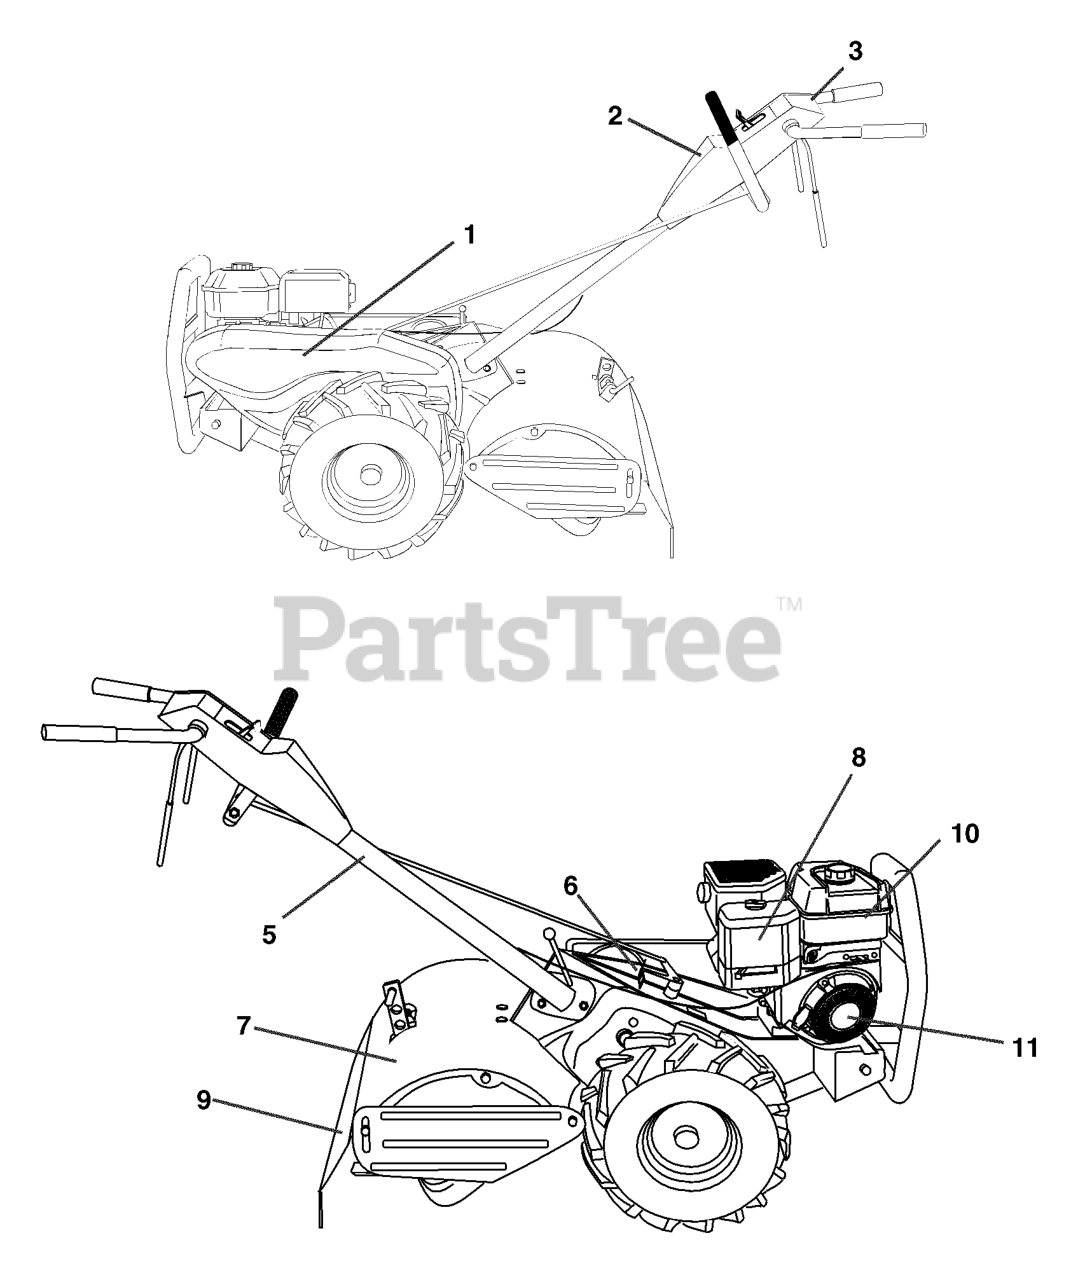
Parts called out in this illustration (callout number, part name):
1	DECAL, BOLT GUARD
2	DECAL, CTRL PANEL
3	DECAL, 650CRT
5	DECAL TI (2 2)
6	DECAL.SHIFT.INDICATOR.TILLER
7	DECAL -CAUTION
8	DECAL, ENG. B&S 6.5HP
9	DECAL TI
10	DECAL, ENG. INTEK
11	DECAL.REWIND
